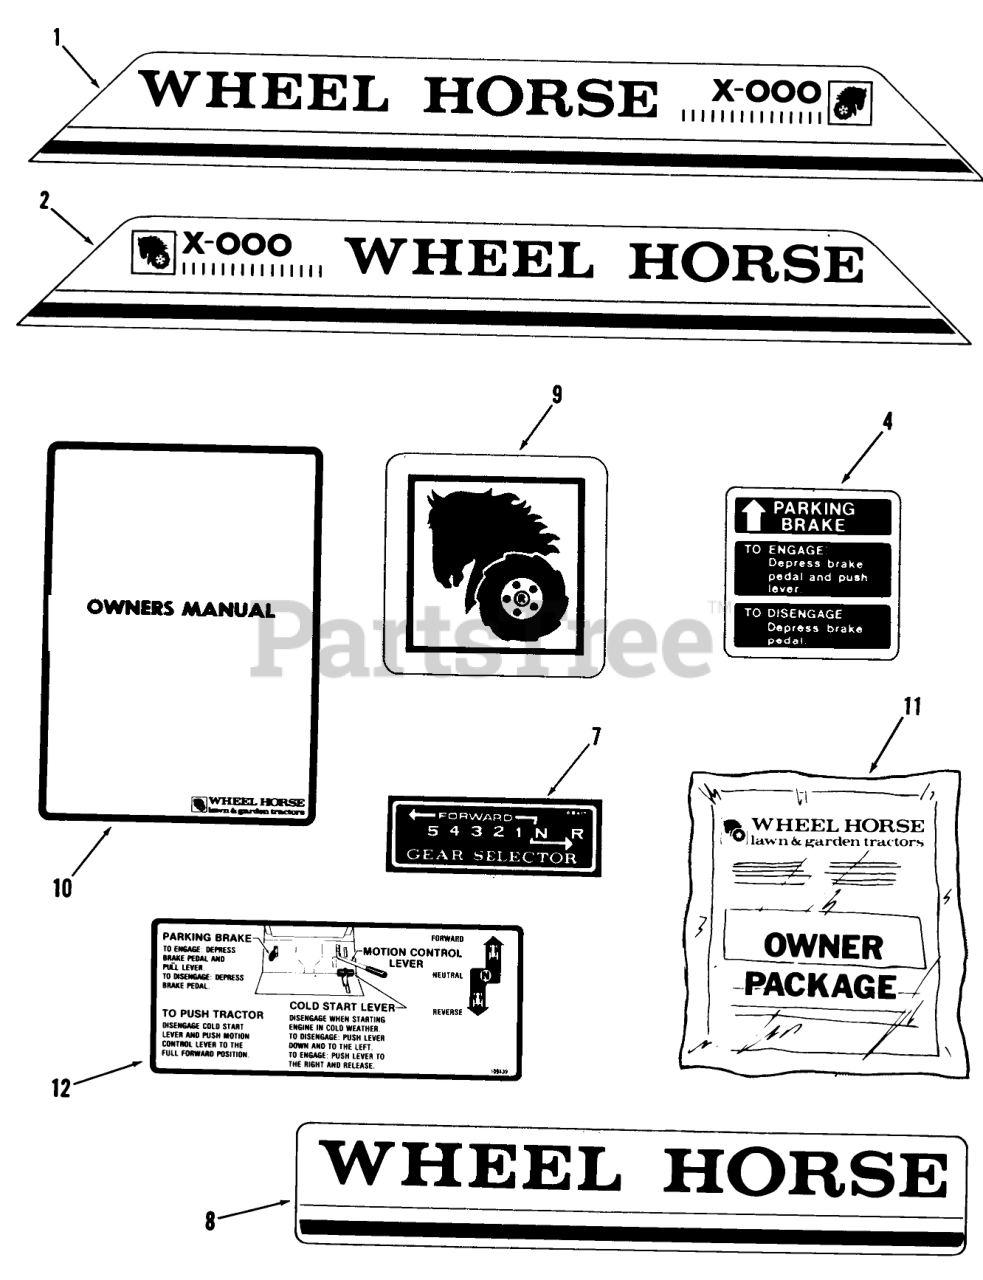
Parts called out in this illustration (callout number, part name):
1	HOOD-DECAL RH
1	DECAL HOOD B-85 RH
1	Decal-Hood RH B-115
1	Decal-Hood RH B-165
2	HOOD-DECAL LH
2	DECAL HOOD B-85 LH
2	DECAL-HOOD B115 LH
2	Decal-Hood LH B-165
4	Decal Parking Brake
7	DECAL-SHIFT
8	DECAL-REAR
9	DECAL-LOGO
10	Owner-s Manual (Alternate 810262R1 5-Speed Only)
11	New Tractor Loose Parts Package B-115 Automatic Only
11	New Tractor Loose Parts Package B-165 Automatic Only
11	New Tractor Loose Parts Package B-85
11	New Tractor Loose Parts Package B-115 5-Speed Only
11	New Tractor Loose Parts Package B-165 5-Speed Only
12	DECAL-SPD CONTROL
